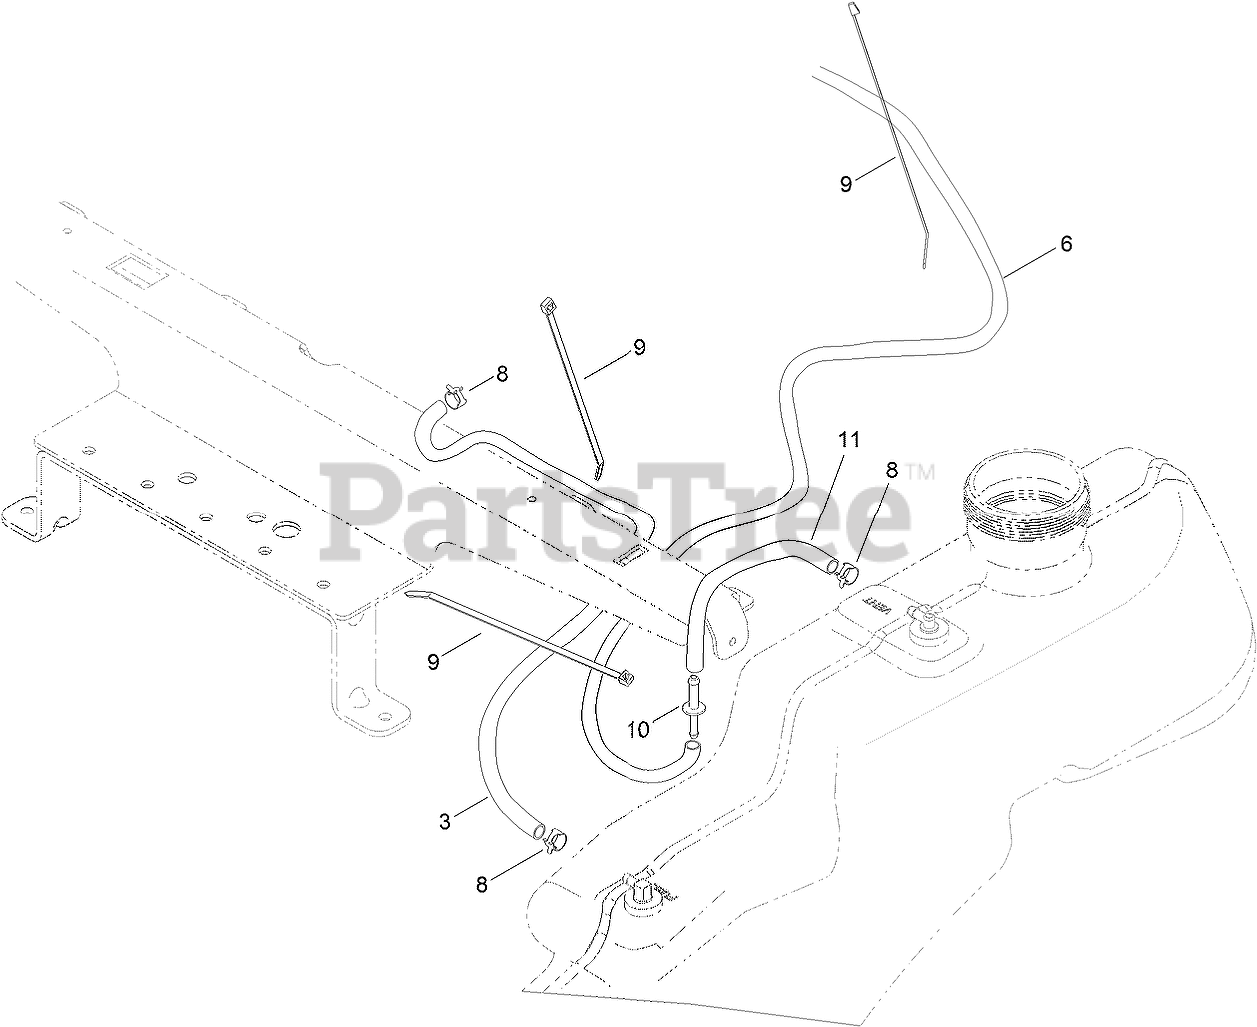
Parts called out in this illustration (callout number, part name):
3	HOSE-FUEL
6	HOSE-FUEL
8	CLAMP-HOSE
9	TIE-CABLE
10	ADAPTOR-ORIFICE
11	HOSE-FUEL
